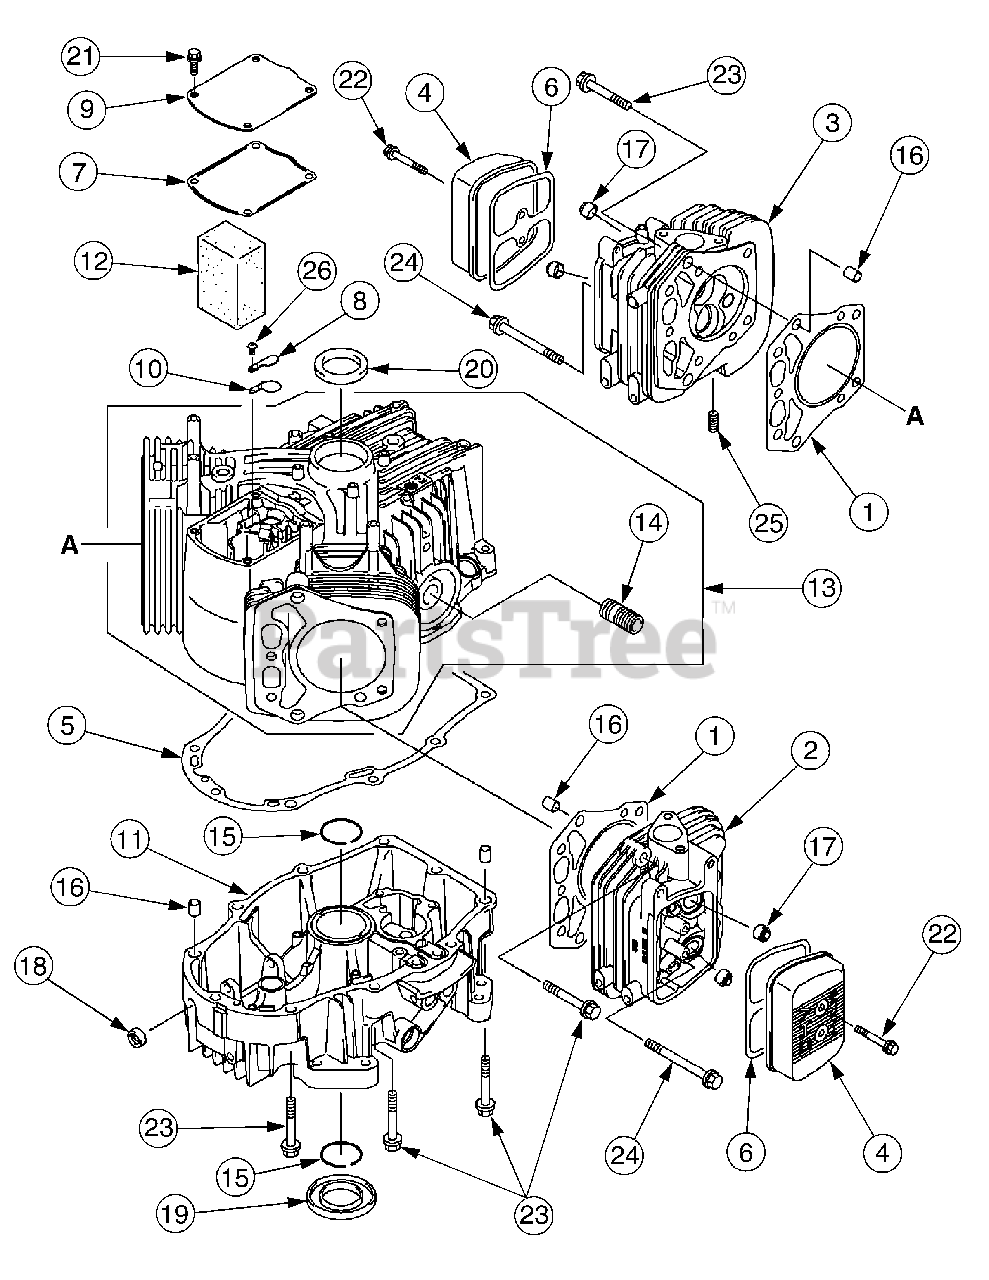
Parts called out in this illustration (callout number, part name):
2	Head, Complete- Cylinder #2
3	Head, Complete- Cylinder #1
4	Case, Rocker
5	Gasket, Crankcase Cover
6	Gasket, Rocker Case
7	Gasket, Breather
11	Cover, Crankcase
12	Element, Breather
13	Crankcase - Complete
17	Seal, Oil, RVC2, 6 x 11 x 10.2
18	Seal, Oil, SO 8 x 14 x 5 HS
19	Seal, OIl, SD 35 x 62 x 8 L HS
20	Seal, Oil, SD 35 x 52 x 7 R HS
21	Bolt, Flanged
22	Bolt, Flanged
23	Bolt, Flanged
24	Bolt, Flanged
25	Bolt, Stud
26	Screw, Pan
